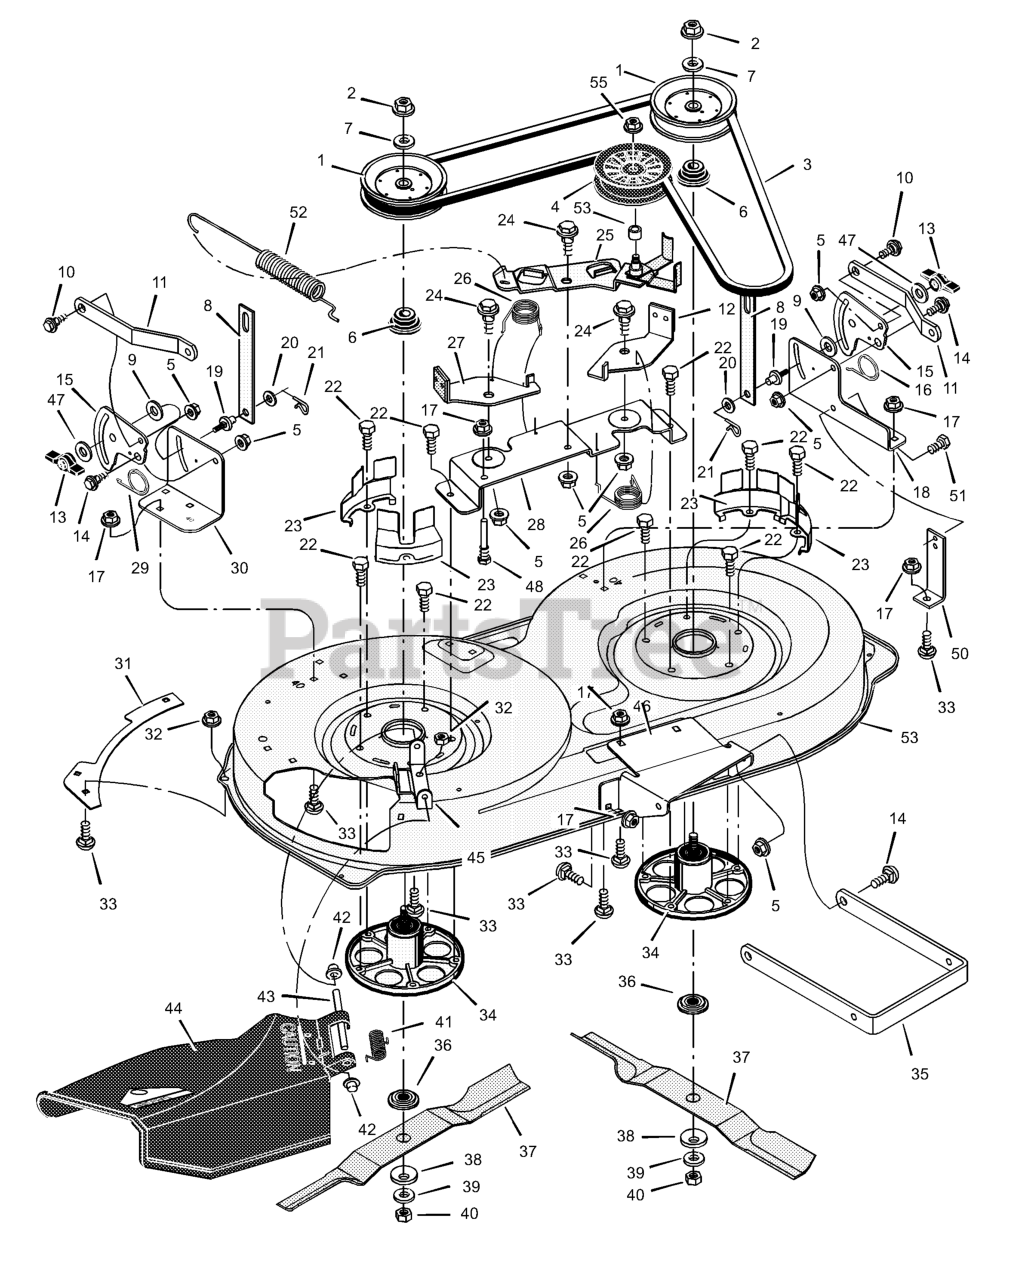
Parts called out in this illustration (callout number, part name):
1	Pulley, Jackshaft
2	Nut, Hex
3	Belt, Mower Drive
4	Pulley, Idler
5	Nut, Flange
6	Spacer, Pulley
7	Washer
8	Link, Lift
9	Pad, Friction
10	Bolt, Shoulder
11	Bracket, Suspension
12	Pad Assembly, Left Brake
13	Knob
14	Bolt, Shoulder
15	Plate, Suspension
17	Nut, Flange
18	Bracket, Suspension
19	Pin, Hanger
21	Pin, Cotter
22	Bolt
23	Cover, Pulley
24	Bolt, Shoulder
25	Arm, Idler
27	Pad Assembly, Right Brake
28	Bracket Assembly, Brake
30	Bracket, Suspension
31	Plate
32	Nut, Flange
33	Bolt, Carriage
34	Mandrell
35	Bracket, Suspension
36	Adapter, Blade
42	Cap, Push On
43	ROD, Deflector
44	Deflector Assembly
45	Bracket, Deflector
46	Bracket, Front Hanger
48	Guide, Belt
50	Bracket, Support
52	Spring, Extension
54	Housing, Blade
55	Nut, Flange
